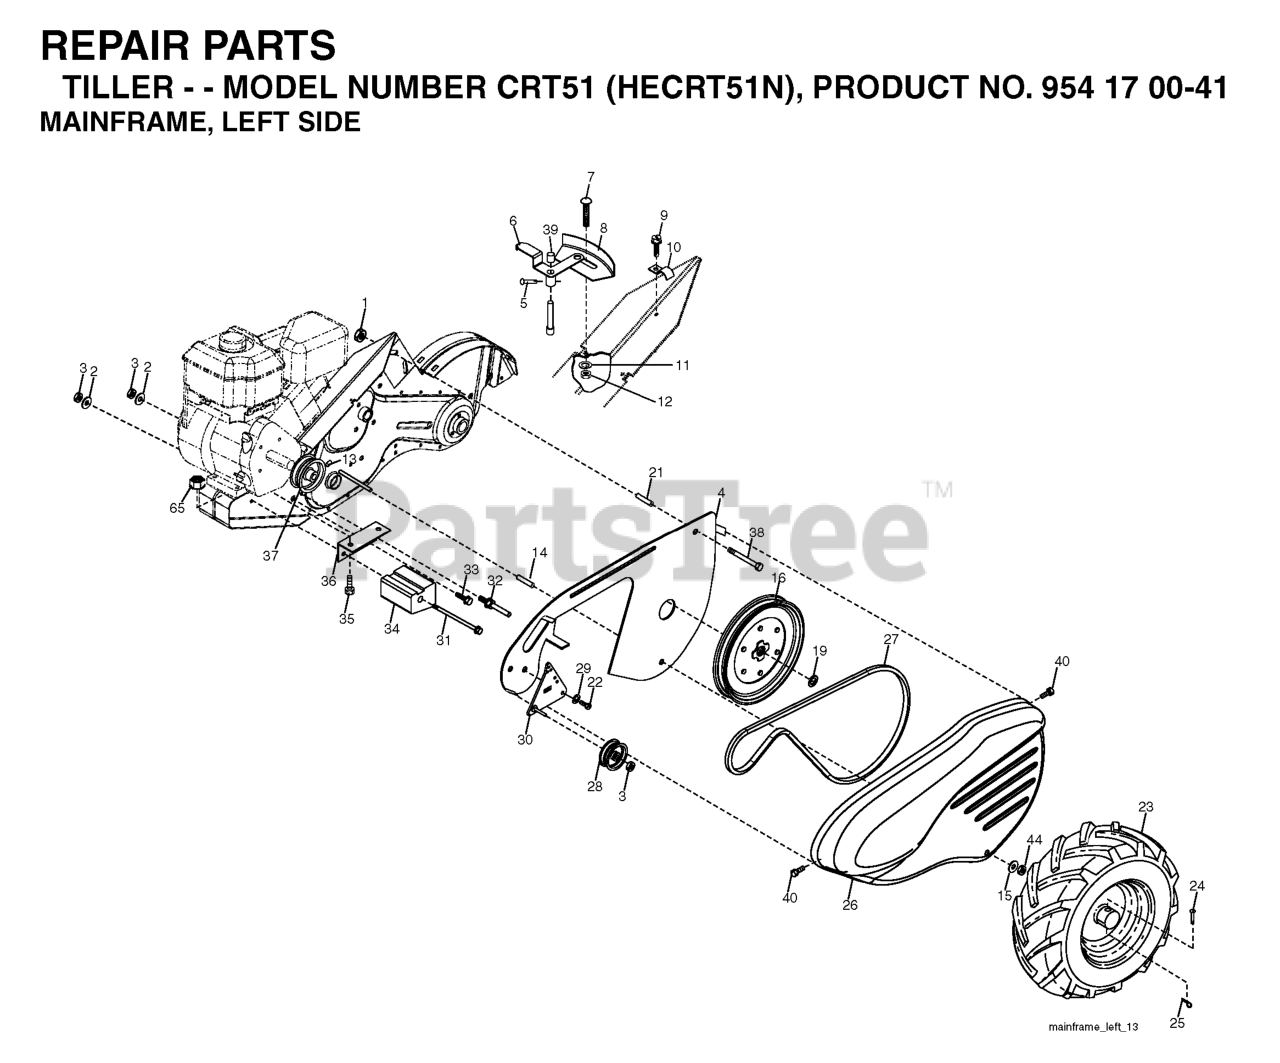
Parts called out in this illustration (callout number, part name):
1	NUT
2	WASHER, LOCK 3/8
3	NUT.HEX.3/8-16UNC
4	SHIELD
5	PIN.SPIROL.FLARED
6	LEVER ASM CRT
8	PANEL.INDICATOR.SHIFT.BLACK
9	TAPPING SCREW
10	CONDUIT.CLIP.PLATED
11	LOCKWASHER
12	NUT
14	SPACER-SPLIT.327 X .42
15	WASHER
16	SHEAVE, TRANSMISSION
19	RETAINING RING LT
21	SPACER CRT
23	TIRE.16X4-8.CHEVRON.TILLER
24	RIVET,DRILLED
25	RETAINER M
26	RP BELT GUARD
27	V-BELT
28	PULLEY-IDLER TI
30	BRACKET.ASM.IDLER.BLACK
31	BOLT.FIN.HEX.3/8-16UNC
32	SHIFT ARM CRT
33	BOLT
34	COUNTERWEIGHT.LH.CRT
35	BOLT, HEX 5/16-18X1-3/4
36	BRACKET LH CRT
37	RP.ENGINE PULLEY
38	BOLT
39	CAP.PLUNGER.BLACK
40	SCREW.HEX.WSH.SLT.#10-24X.50
44	NUT.71038.31-18.HEX.NYLOCK
65	LOCKNUT-FLANGE 5/16-18
